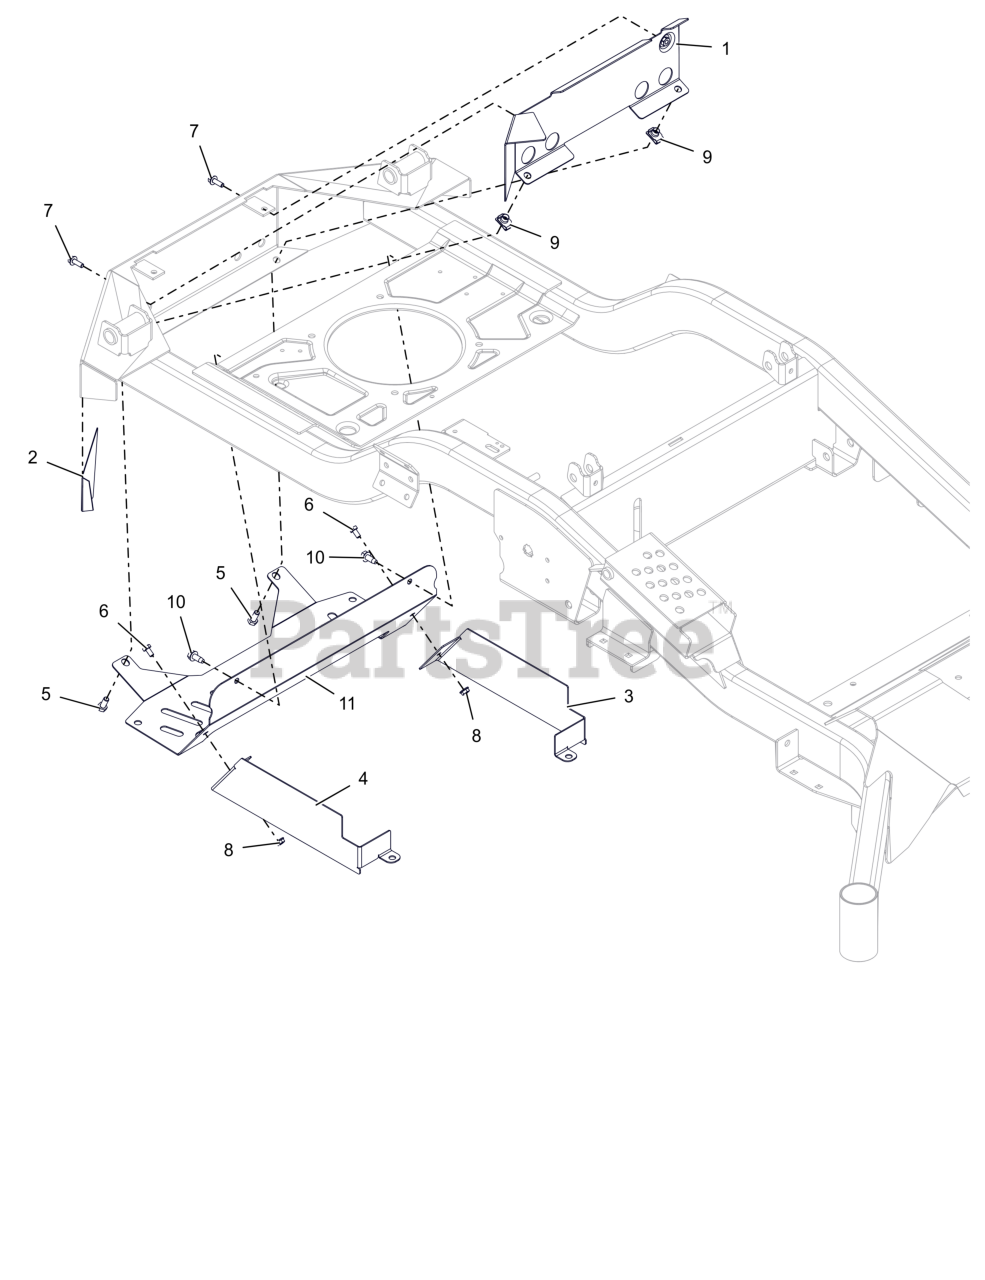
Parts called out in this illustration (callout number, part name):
1	WMT, HEAT BAFFLE
2	TAPE, HEAT DEFLECTOR
3	GUARD,REAR CLUTCH LH
4	GUARD,REAR CLUTCH RH
5	BLT,HEX .31-18X.75 G5 ZCC
6	BLT,HEX .25-20X.50 G5 ZCC
7	BLT,HEX-FLG .25-20X.75 G5 BFP
8	NUT-LK-TOP-FLG .250-20 GF ZCC
9	NUT-CLIP RETAINER 5/16-18X.56
10	SCR,TAP .312-18X.75 HWH TR ZCC
11	SHIELD, HEAT (HD)
